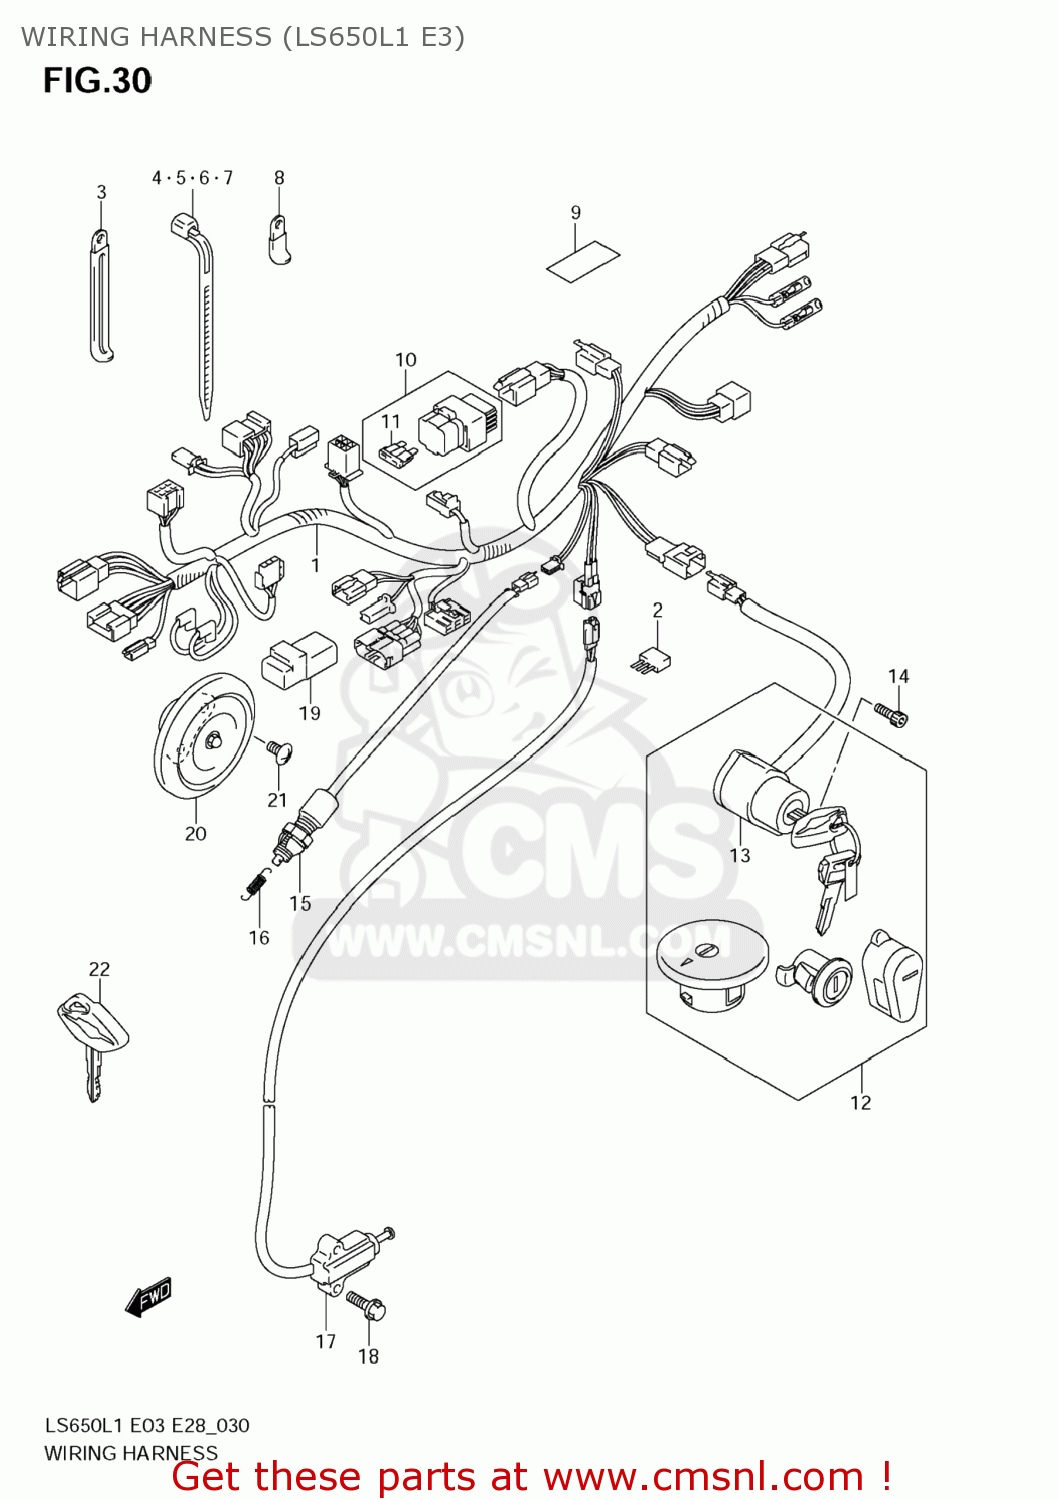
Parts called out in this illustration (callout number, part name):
1	HARNESS,WIRING
2	DIODE(STANLEY DE8804)
3	CLAMP(L:80)
4	CLAMP(L:95)
5	CLAMP(L:125)
6	CLAMP(L:165)
7	CLAMP(L:235)
8	CLAMP,WIRING HARNESS
9	COVER
10	BOX ASSY,FUSE
11	FUSE(20A)
12	LOCK SET
13	SWITCH ASSY,IGNITION
14	BOLT
15	SWITCH ASSY,STOP LAMP
16	SPRING
17	SWITCH ASSY,SIDE STAND WARNING
18	BOLT
19	RELAY ASSY
20	HORN ASSY
21	SCREW
22	KEY,BLANK(TYPE:C)
